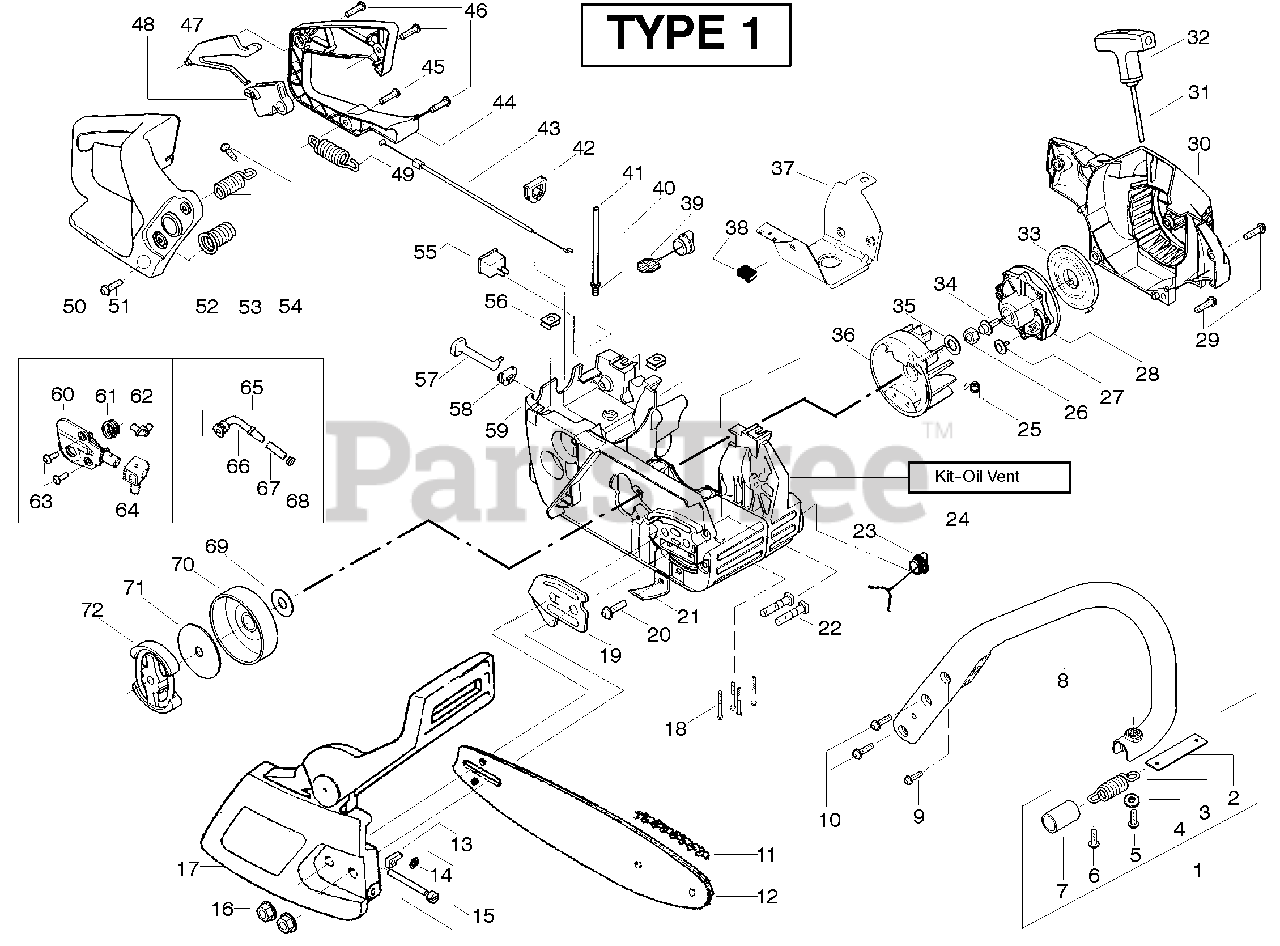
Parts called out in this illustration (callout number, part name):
1	Assy.- Isolator
2	Limiter Strap
3	Spring- Isolator
7	Sleeve-AV Spring
8	Front Handle
11	Chain-18"
13	Pin-Bar Adjust
14	Retainer-Bar Adjust
15	Kit-Bar Adj.
16	Nut-Bar Mounting
17	Kit-Chain Brake
19	Plate-Bar Mounting
21	Chain Catcher
22	Bolt-Bar
23	Oil Cap Ass'y.
24	Kit-Oil Vent
25	Spring-Starter Dog
26	Nut- Flywheel
28	Starter Pulley
30	Fan Housing
31	Kit - Rope
32	Starter Handle
33	Recoil Spring
35	Washer- Flywheel
36	Assy- Flywheel
37	Shield - Heat
38	Clip - "U"
39	Fuel Cap Ass'y.
40	Fitting- fuel line
41	Kit-Fuel line (large)
42	Grommet-Cable
43	Cable-Throttle
44	Cover-Rear Handle
47	Throttle Lockout
48	Trigger-Throttle
49	Spring- Isolator
50	Handle - Rear
52	Assy. Isolator - lower
53	Kit- Isolator (Upper)
55	Kit-Switch
56	Nut- "U"-Type
57	Knob-Choke
58	Grommet-Knob
59	Assy-Chassis
60	Kit - Oil Pump
61	Gear-Worm Spring
62	Elbow-Oil Pickup
64	Seal Block
65	Assy-Oil Pick-up
66	Pick-up Oiler
67	Oil Filter
68	Plug-Oil Filter
69	Washer-Thrust
70	Assy.-Clutch Drum w/bearing
71	Washer-Clutch
72	Assy. Clutch
